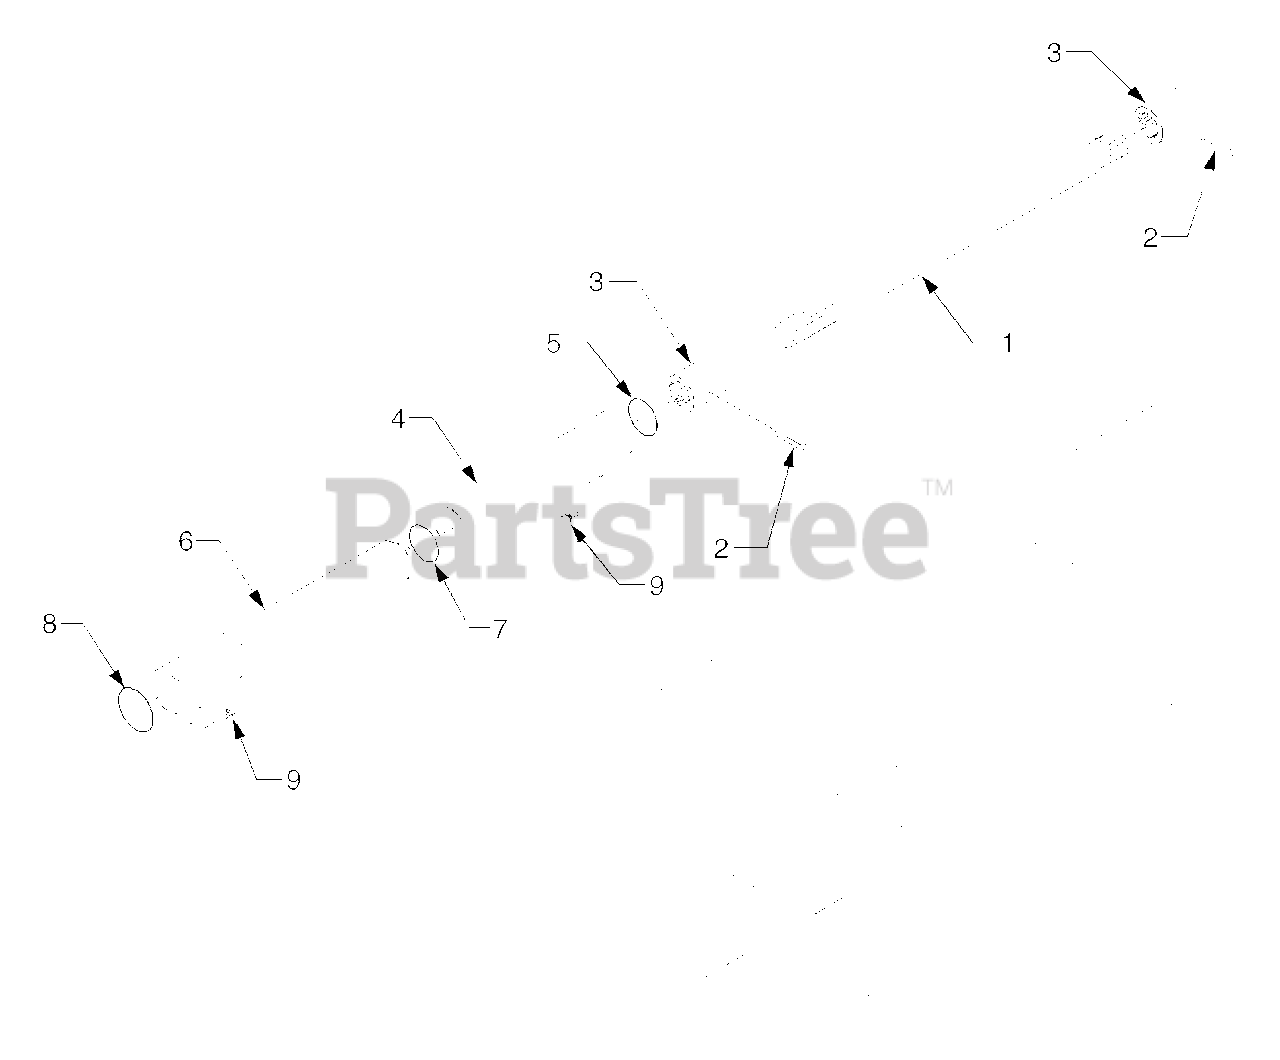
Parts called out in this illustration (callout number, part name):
1	Shaft 2, Propeller
4	Cover, Propeller
6	Cover 2, Propeller
